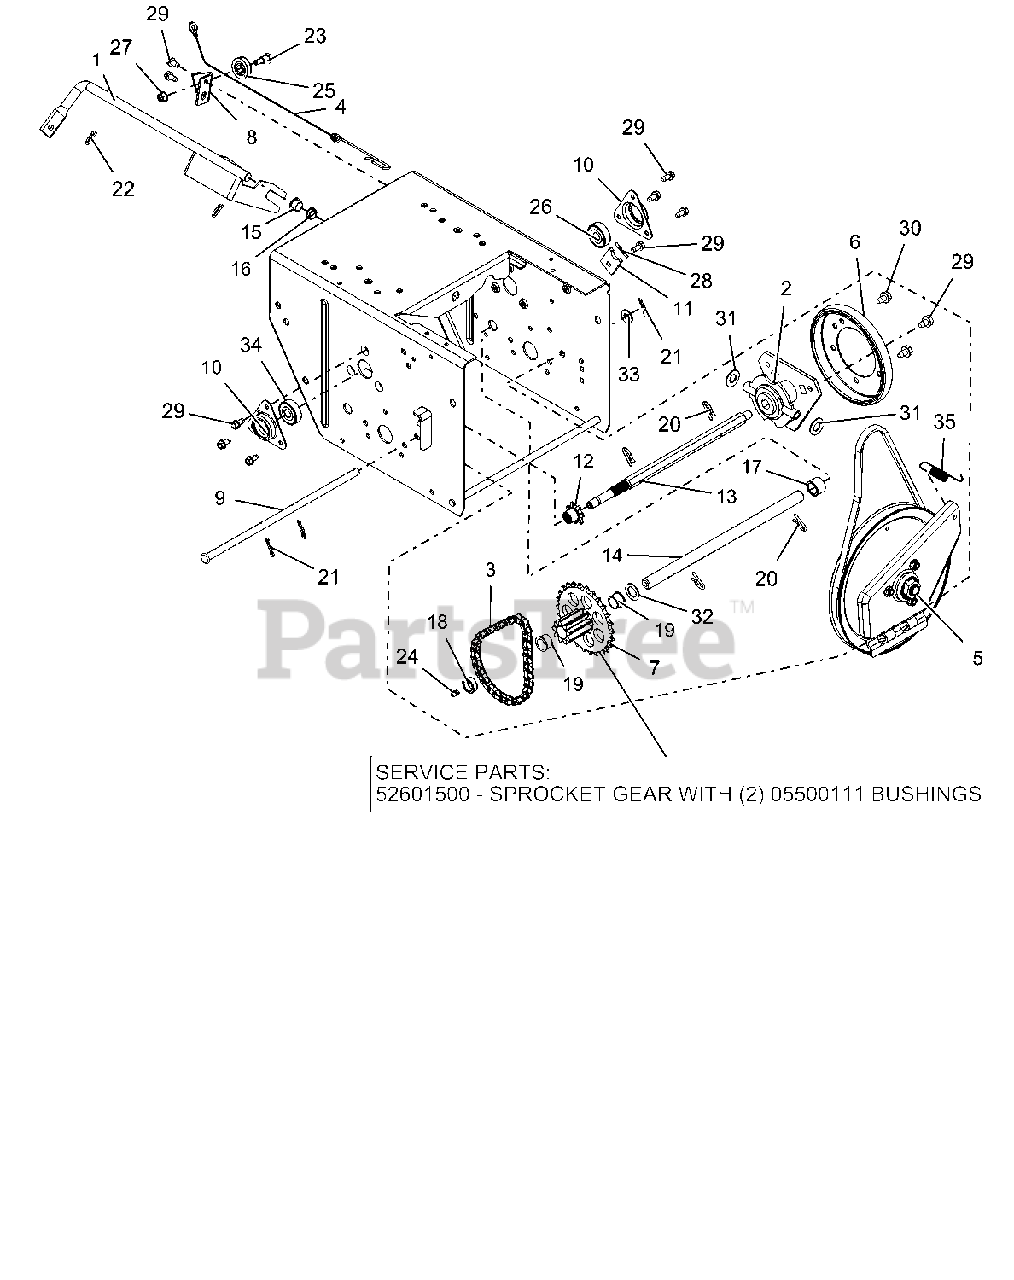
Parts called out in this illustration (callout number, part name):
1	ARM, SHIFT-WELDMENT
2	CARRIER, DRIVE DISK
3	CHAIN - #41, 32 PITCHES
4	CABLE, LOWER TRACTION,SS & PRO
5	PLATE, SWING ASSEMBLY-DEEP
6	FRICTION, DISC
7	PINION & SPROCKET
8	BRACKET, CABLE PULLEY
9	PIN, PIVOT
10	FLANGE, BEARING
11	TAB, ANTI ROTATION
12	SPROCKET, PINION 7T W/SPLINE
13	SHAFT, HEX-W/SPLINE TRACK
14	SHAFT, PINION - HARDENED
15	BUSHING, POLYLINER-.50 SPLIT
16	BUSHING, POLYLINER-.50 SNAPIN
17	SPACER, .635X.880X.611
18	BSHG-SLV, .635X.880X.305
19	BSHG-FLG .625X.750X.500X.875
20	PIN, SPRING CLIP
21	PIN-HAIR, ENDRIES #25 YWZC
22	CLIP, SPRING
23	BOLT, SHLDR-.375X.375X.25-20
24	ZERK,FITTING .25X.125 DRIVE IN
25	PULLEY, CABLE
26	BRG-BALL .669X1.575X.47(6203Y)
27	@NUT-LK-TOP-FLG .31-18 YWZC
28	@PIN-GRV .125X1.00 TP E ALLOY
29	SCR-TAP .25-20X.50 HWH TR YWZ
30	@SCR-TAP .31-18X.50 HWH TR YWZ
31	WSHR-FL-STL .505X1.00X.062YWZC
32	WSHR-FL-STL .406X1.00X.188 YWZ
33	@WSHR-FL-STL.406X.812X.065 YWZ
34	BRG-BALL .437X1.375X.437
35	SG-TENS .048X.50X2.8
36	PINION & SPROCKET W/BUSHINGS
